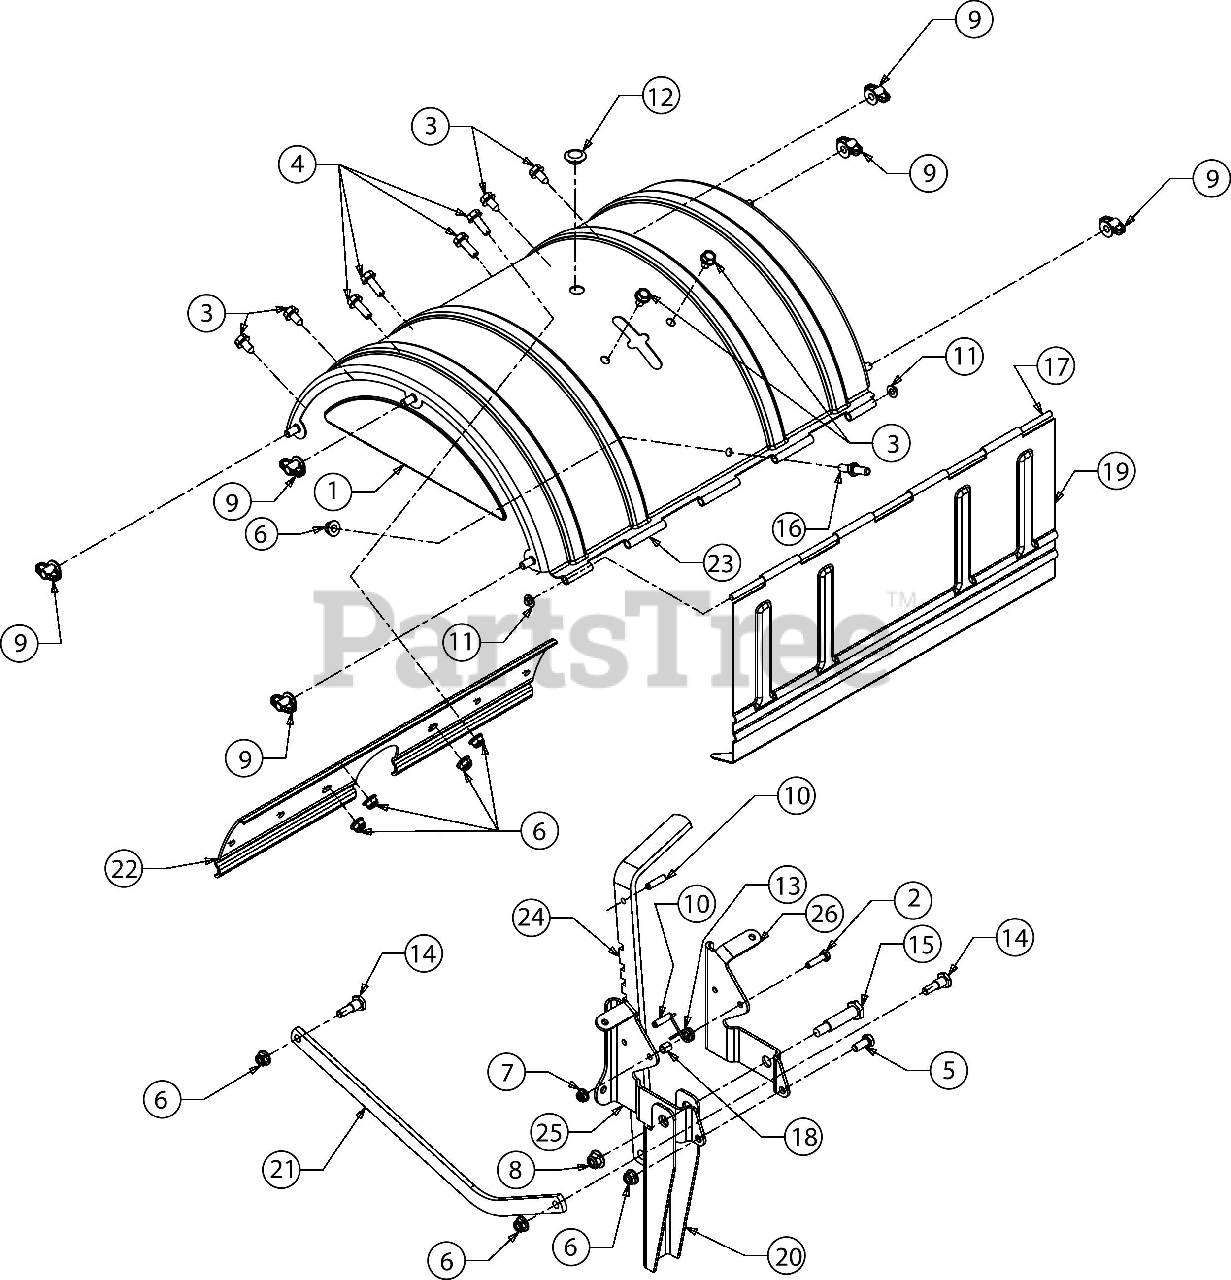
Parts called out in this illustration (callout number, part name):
1	END COVER ASSEMBLY
2	SCREW 1/4-20 X1.00 GR5
3	SCREW 5/16-18 X .625
4	SCREW 5/16-18 X .875 GR5
5	SCREW 5/16-18 x .75 GR5
6	FLANGE LOCK NUT 5/16-18
7	FLANGE LOCK NUT
9	WING NUT 5/16-18
10	SPRING PIN 1/4 X 1.00
11	PUSH NUT
12	DECK HOLE PLUG
13	TORSION SPRING
14	SHOULDER SCREW
15	SHOULDER BOLT .498 X 1.635:3/8-16
16	SHOULDER SCREW
17	TILLER FLAP ROD
18	ROUND SPACER
19	REAR TINE SHIELD
20	REVERSE STOP ARM
21	DEPTH DRAG BAR
22	TINE BRACKET
23	TINE SHIELD
24	DEPTH ADJUSTMENT BRACKET
25	TAIL BRACKET (LH)
26	TAIL BRACKET (RH)
